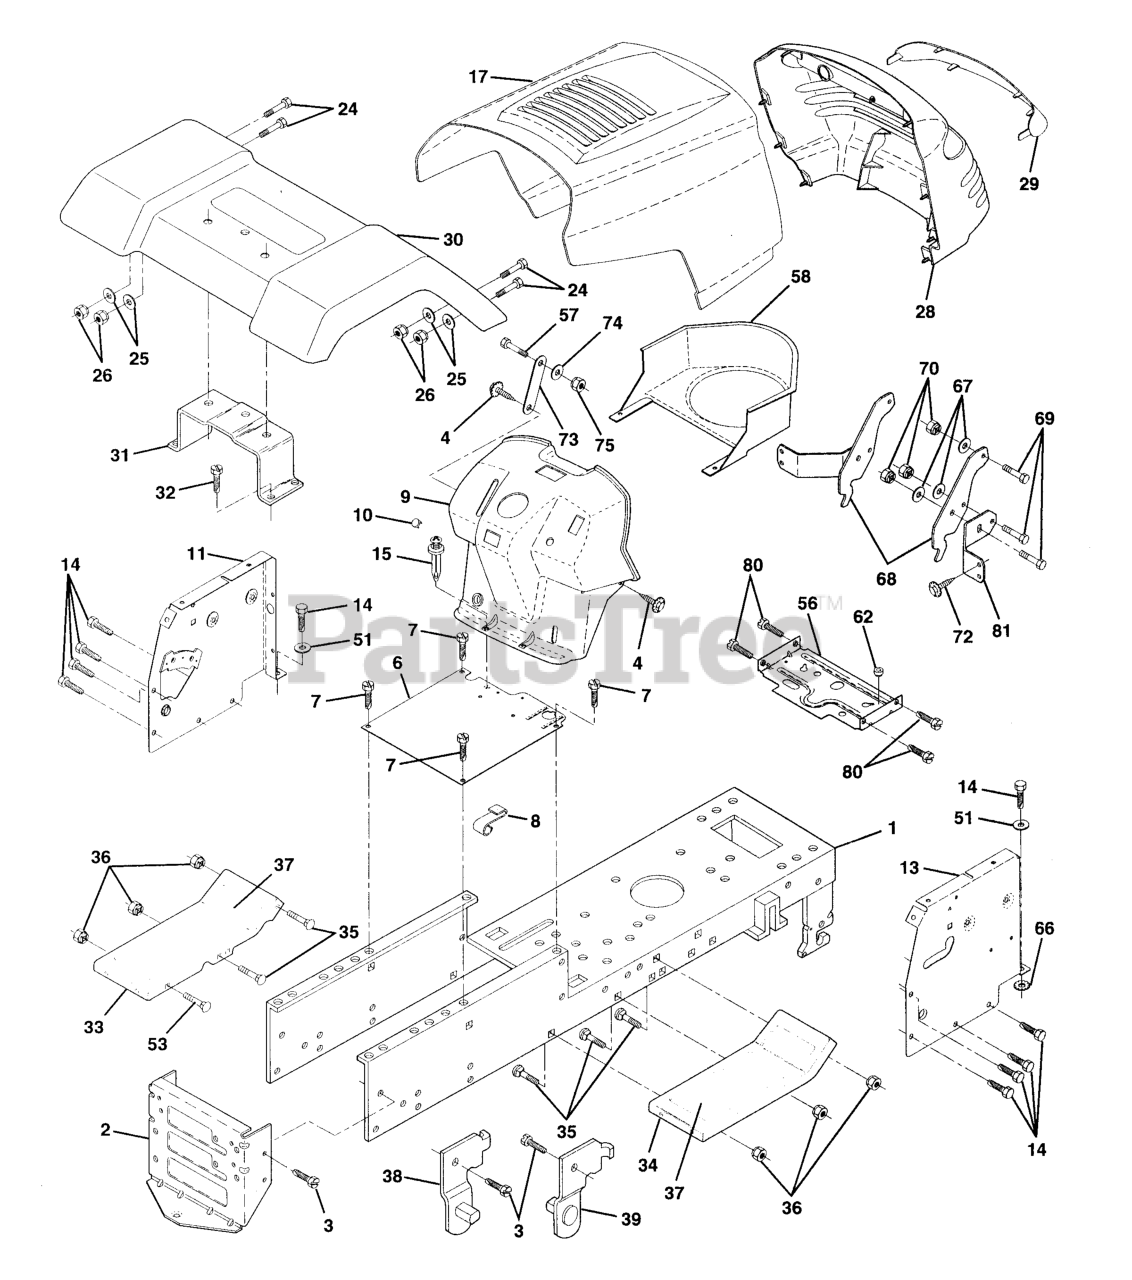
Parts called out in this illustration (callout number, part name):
1	CHASSIS
2	STRETCH DRAWBAR
3	SCREW
4	SCREW HEX CRT
6	SADDLE BRACKET
7	SCREW
10	PLUG BUTTON T
11	DASH PANEL LH
13	DASH PANEL RH
14	SCREW LT
15	RIVET PUSH
17	HOOD
24	BOLT
25	WASHER
26	NUT
28	GRILL
30	FENDER
31	BRACKET FENDER
32	SCREW
33	ROLL PIN NLA
34	PAD,SPACER
35	BOLT
37	FOOTREST PAD
38	BRACKET LH PIVOT
39	BRACKET RH PIVOT
51	Washer 13/32 x 3/4 x 16 Ga.
53	BOLT D
56	BATTERY SUPPORT
57	BOLT
58	AIR DUCT
62	BUSHING.SNAP.NYL.BLK.
66	LOCKWASHER
67	WASHER
68	HINGE HOOD
69	BOLT.HEX.1/4.X.3/4.DICHROMATE
70	NUT.CROWNLOCK.1/4
72	SCREW
74	WASHER
75	LOCKNUT.NYLOC.1/4-20
80	SCREW.THDROL.5/16-18X3/4.TTY
81	BRACKET GRILL
